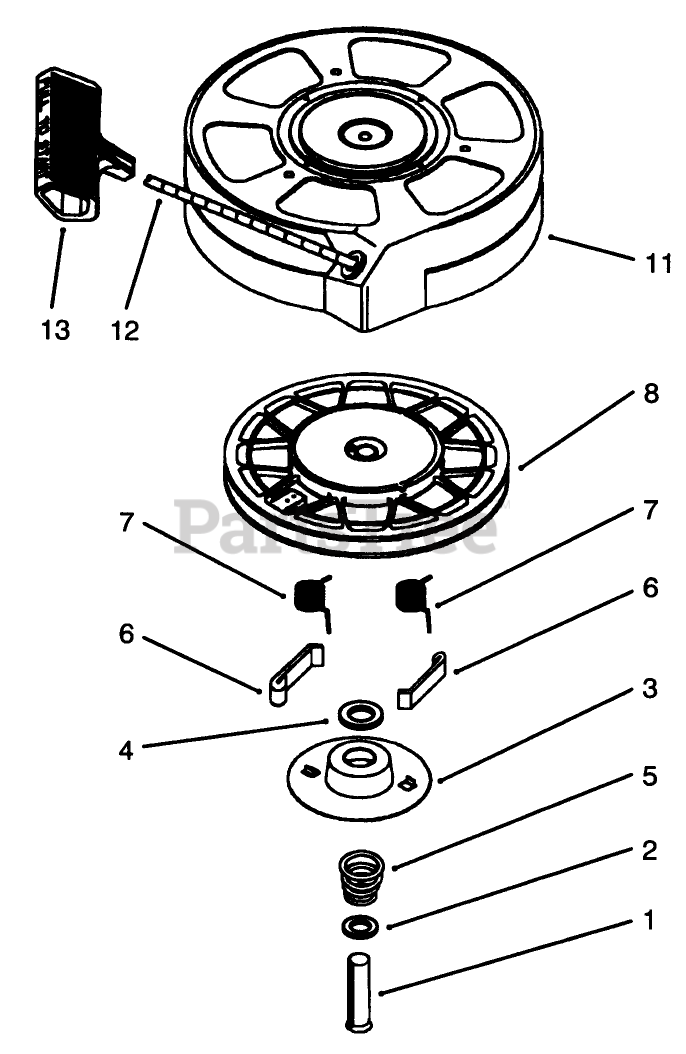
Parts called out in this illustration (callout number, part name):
1	Pin, Spring (Incl. Ref. #7)
2	Washer
3	Retainer
4	Washer
5	Spring-Brake
6	Dog-Starter
7	Spring-Dog
8	Pulley and Rewind Spring ASM
11	Housing Ass-y-Starter
12	Rope-Starter (98 cut to length)
13	Handle-Starter (STD)
